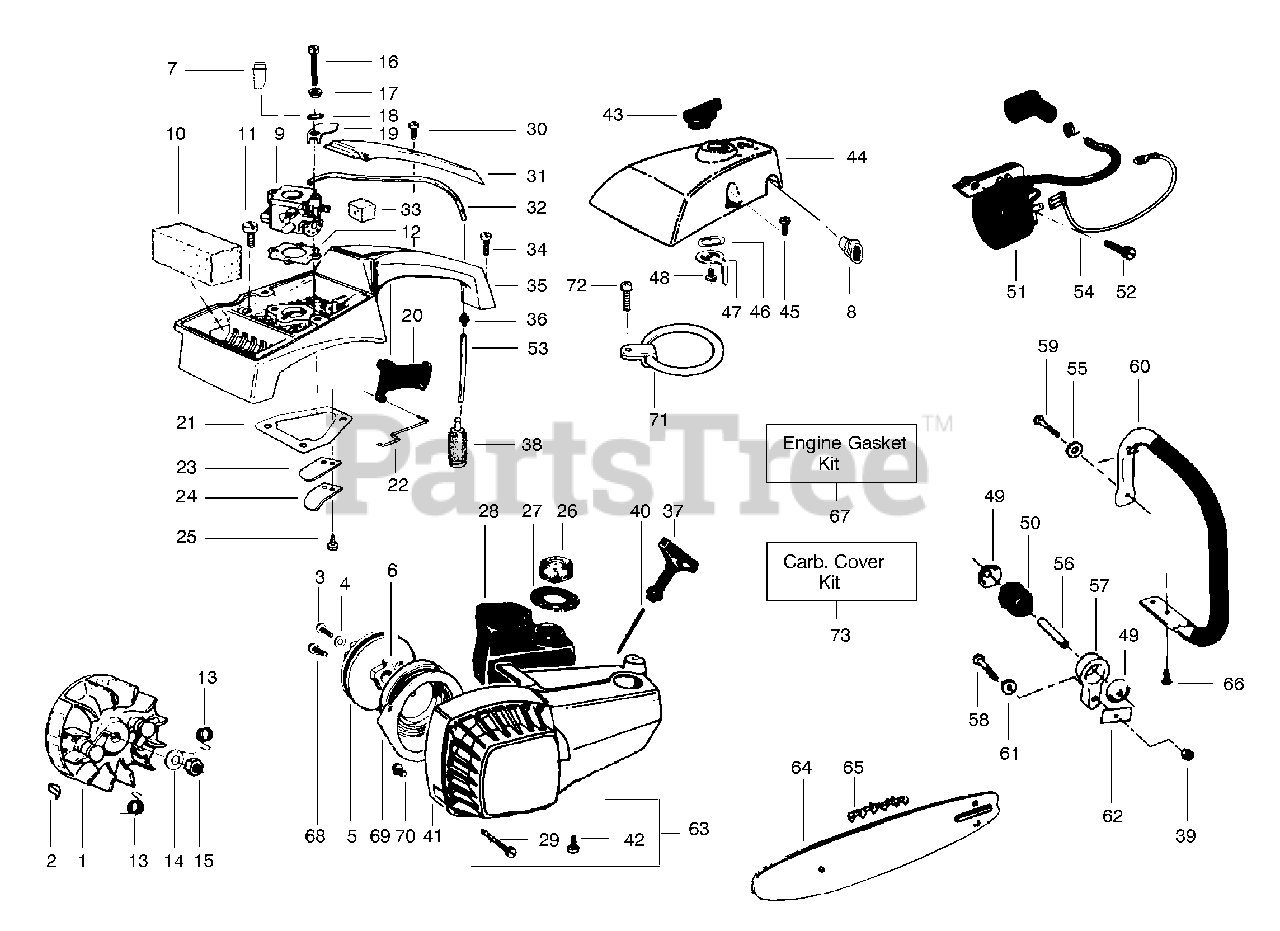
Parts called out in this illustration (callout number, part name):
1	Flywheel Ass'y.
2	Flywheel Key
3	Pulley Retaining Screw
5	Starter Pulley
6	Starter Spring
7	Grommet-Idle
8	Grommet-Mixture
9	Carburetor Kit w/Limiter Caps
10	Air Filter
13	Starter Dog Spring
14	Flywheel Washer
19	Choke Shutter
20	Throttle Trigger
22	Throttle Wire
23	Reed Valve
24	Reed Stop
26	Fuel Cap Ass'y.
27	Seal-Fuel Tank
28	Fuel Tank Ass'y.
31	Handle Cover Ass'y.
32	Line Kit
33	Throttle Wire Boot
35	Carb. Handle Hsg.
36	Fuel Line Fitting
37	Starter Handle
38	Fuel Pick-up Ass'y.
40	Rope Kit
41	Fan Hsg. Kit
43	Choke Knob
44	Carb. Cover
46	Wave Washer
47	Choke Lever
49	Isolator Cup
50	Isolator
51	Ignition Module Kit
53	Fuel Line Kit
54	Switch Lead
57	Bracket-Isolator
60	Handlebar Ass'y.
62	Isolation Pad
63	Fan Hsg. Screw Kit
64	Bar
65	Chain
67	Engine Gasket Kit
68	Rope Retaining Screw
69	Air Baffle
71	Rope Ring Kit
73	Kit-Carb. Cover
